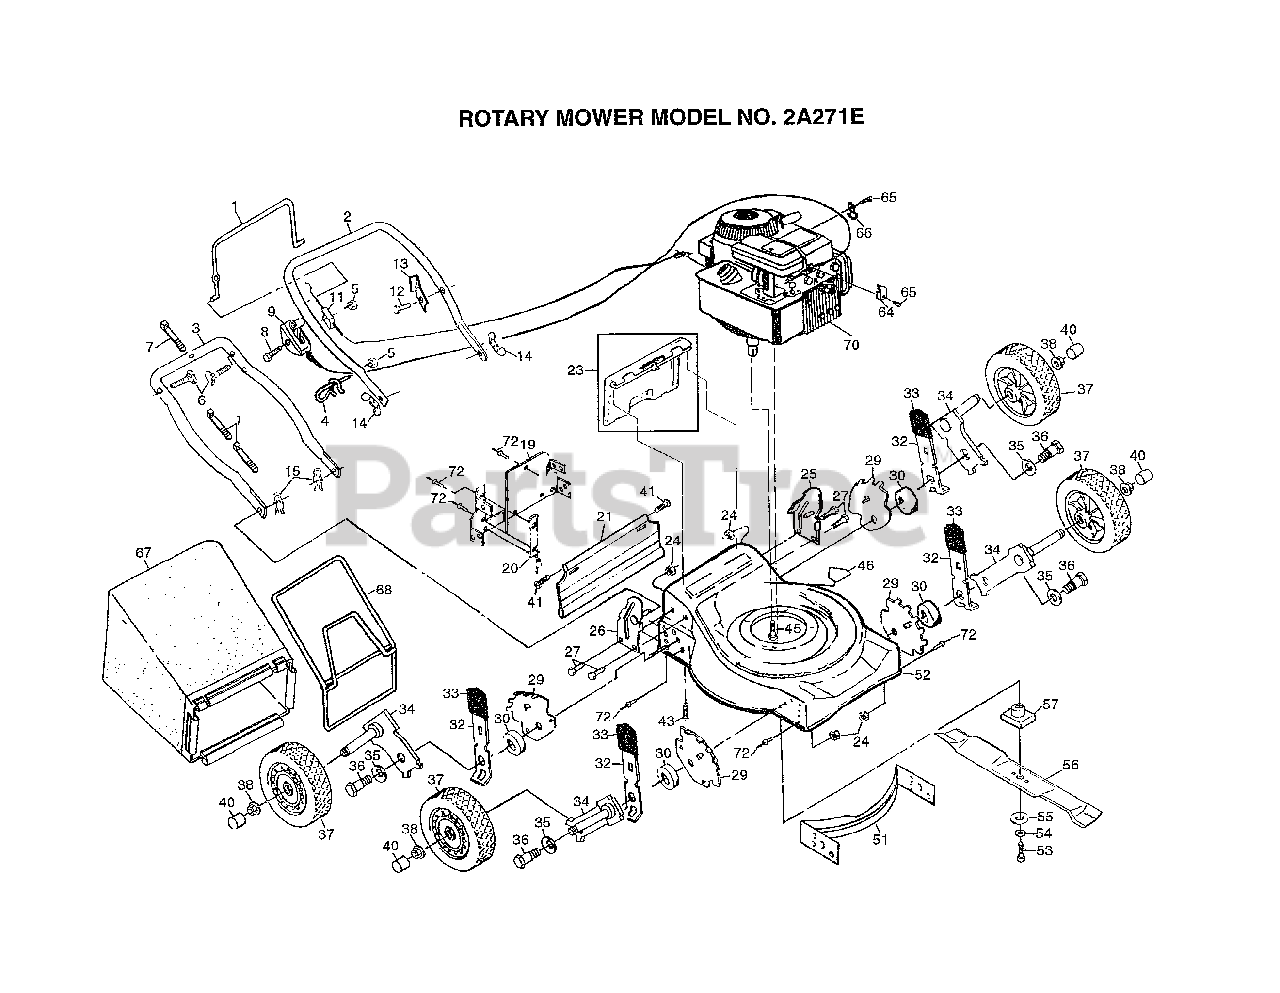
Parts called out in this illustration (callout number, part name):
1	CONTROL BAR
4	ROPE GUIDE
6	BOLT.HANDLE.LM
8	SCREW.HXHD.WASH.
9	CONTROL THROTTLE
11	"CABLE,ENG ZONE CO"
12	TAPPING SCREW
13	"BRKT,UPSTOP"
14	"NUT,WING PM"
15	HAIRPIN COTTER
19	PLATE.BACK.20RD
21	SKIRT.PUSH.20RD
23	KIT.DOOR.RR.20STL
24	LOCKNUT PM
27	SCREW
29	BRACKET.WHL.ADJ.9
32	SPRING SELECTOR
33	KNOB PM
34	ARM.AXLE.ASM.BZP.
35	"WASHER, BELLEVIL."
36	BOLT SHLD 3/8-16
37	WHEEL.ASM
38	HEX FLANGE LOCKNT
40	HUB CAP-PLASTIC
41	HINGE SCREW
43	SCREW
45	SCREW
46	DECAL HYT
53	SCREW
54	LOCKWASHER
55	"WASHER,HARDEN"
56	BLADE.20.MULCH.AY
57	BLADE ADAPTOR
64	CABLE CLAMP
65	SCREW PM
66	GUIDE CLIP PM
67	GRASSBAG.250B1.BL
68	FRAME.CATCHER.2.5
72	BLIND RIVET
